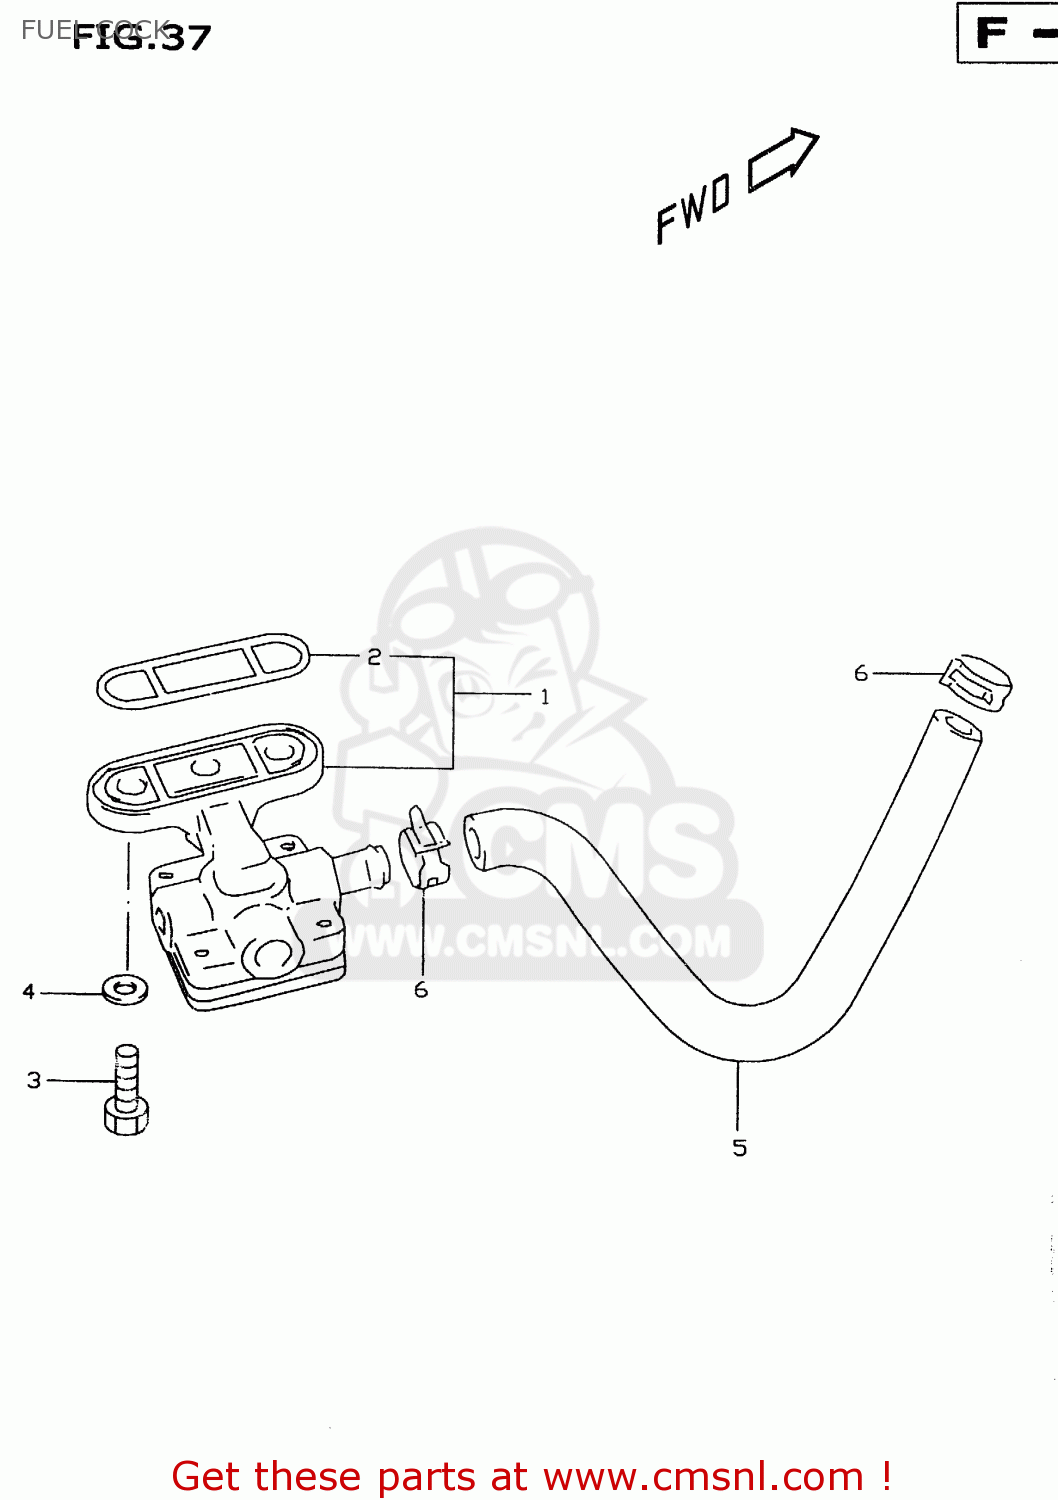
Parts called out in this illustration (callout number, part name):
1	COCK ASSEMBLY,FUEL
2	O RING,JOINT
3	BOLT(6X20)
4	GASKET(6.4X11.5X0.8) (NAS)
5	HOSE(7X12X600)
6	CLIP
